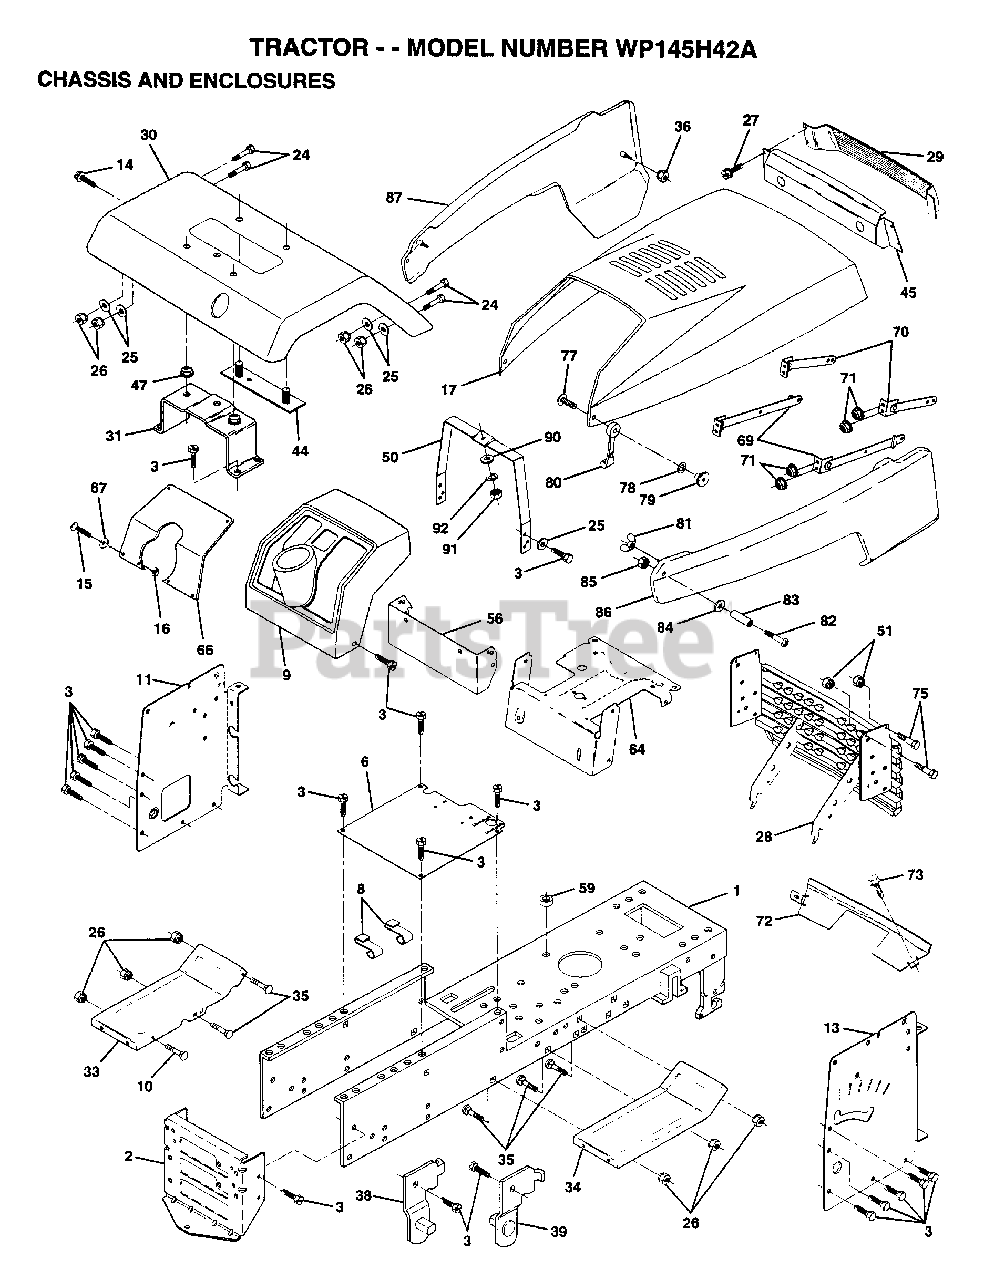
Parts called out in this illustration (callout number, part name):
1	CHASSIS.WLD.11GA
3	SCREW
8	"CLIP,INSULATOR"
9	DASHBOARD BLACK
11	PANEL.DASH.LH.
13	PANEL.DASH.RH.
14	SCREW LT
15	SCREW
24	BOLT
25	WASHER
26	NUT
29	LENS.BAR.CLEAR
30	FENDER.PNT.
31	BRKT.ASM.FENDER
33	FOOTREST.LH.LT/GT
34	FOOTREST.RH.LT/GT
35	BOLT
36	PAL NUT LT
38	BRACKET ASM LH
39	BRACKET ASM RH
44	STRAP ASM FENDER
47	NUT-PUSH YT
50	DASH.SUPT.YP/HUSQ
56	DASH.EXT.PNT.
66	PLATE.DASH.SILKSC
67	WASHER
71	NUT HXKEP 1/4X20
72	STRAP.GRILLE.PNT.
73	SCREW CRT
77	SCREW
78	WASHER LOCK #10
79	WELDNUT
80	HOOD LATCH T
82	SCREW
83	SPACER LT
84	WASHER
87	"PANEL,SIDE LH"
90	WASHER PM
92	LOCKWASHER
